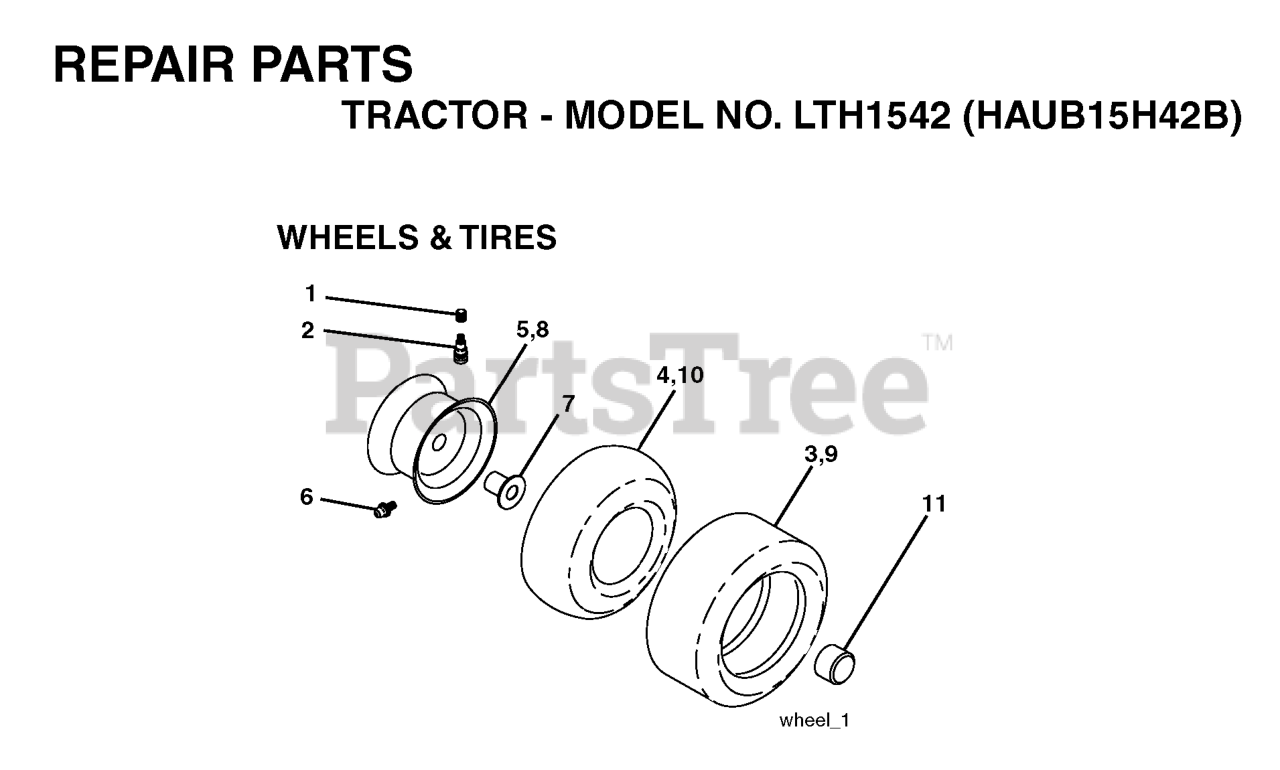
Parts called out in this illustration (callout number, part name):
2	VALVE STEM LT
3	TIRE HEAVY DUTY
4	TUBE.5.3/4.5/6
5	RIM ASM 6" FRONT SILVER
6	FITTING LT
7	BEARING T
8	RIM ASM 8" REAR SILVER
9	TIRE HEAVY DUTY
10	TUBE
11	CAP, AXLE BLK
